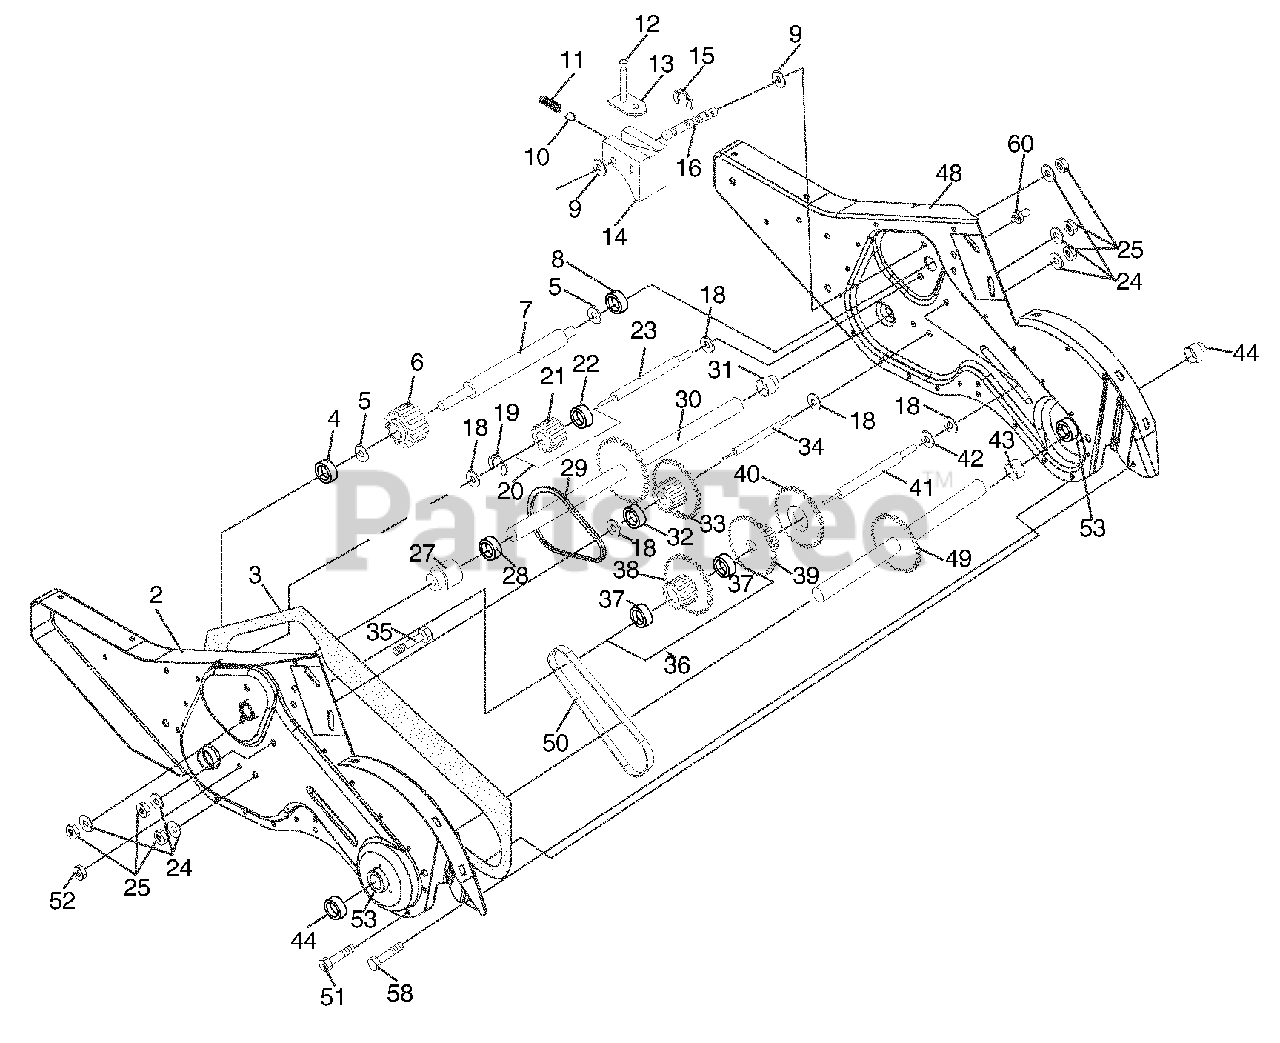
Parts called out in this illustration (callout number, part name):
1	Transmission Assembly
2	Gearcase, L.H. w/Bearing
3	Gasket, Gearcase
4	Bearing, Needle
5	Washer, Thrust 5/8 x 1.10 x 1/32
6	Pinion, Input
7	Shaft, Input
8	Bearing, Needle
9	Washer, Seal
10	Ball, Steel
11	Spring, Shift, Fork
12	O-Ring
13	Arm,. Shift
14	Fork, Shift
15	Ring, Klip
16	Shaft, Shift
18	Washer
19	Ring, Klip
20	Gear, Assembly, Reverse Idler
21	Gear, Reverse Idler
22	Bearing, Needle
23	Shaft, Reverse Idler
24	Washer, Lock 7/16
25	Nut, Hex 7/16-20
27	Bearing, Shaft, Ground Drive
28	Spacer 0.765 x 1.125 x 1.23
29	Chain #35-50 Pitch
30	Ground Shaft Assembly
31	Bearing, Shaft, Ground Drive
32	Spacer 0.70 x 1.00 x 1.150
33	Sprocket and Gear Assembly
34	Shaft, Reduction (2nd)
35	Screw, Whiz, Lock 5/16-18 x 3-1/2
36	Sprocket Assembly w/Bearing
37	Bearing, Needle
38	Sprocket, Tine
39	Gear, Cluster, Red 1st & 2nd
40	Gear, Reverse
41	Shaft, Reduction (1st)
42	Washer, Thrust
43	Spacer 1.01 x 1.75 x 0.760
44	Seal Asm, Oil
48	Gearcase, R.H. w/Bearing
49	Shaft, Tine
50	Chain, Roller #50-50 Pitch
51	Screw 1/4-20 x 1/2
52	Nut, Hex 5/16-18
53	Kit, Bearing, Tine Shaft
58	Bolt Shoulder 1/4-20 x 7/8
60	Fitting Grease
60	Grease, Plastilube #1
